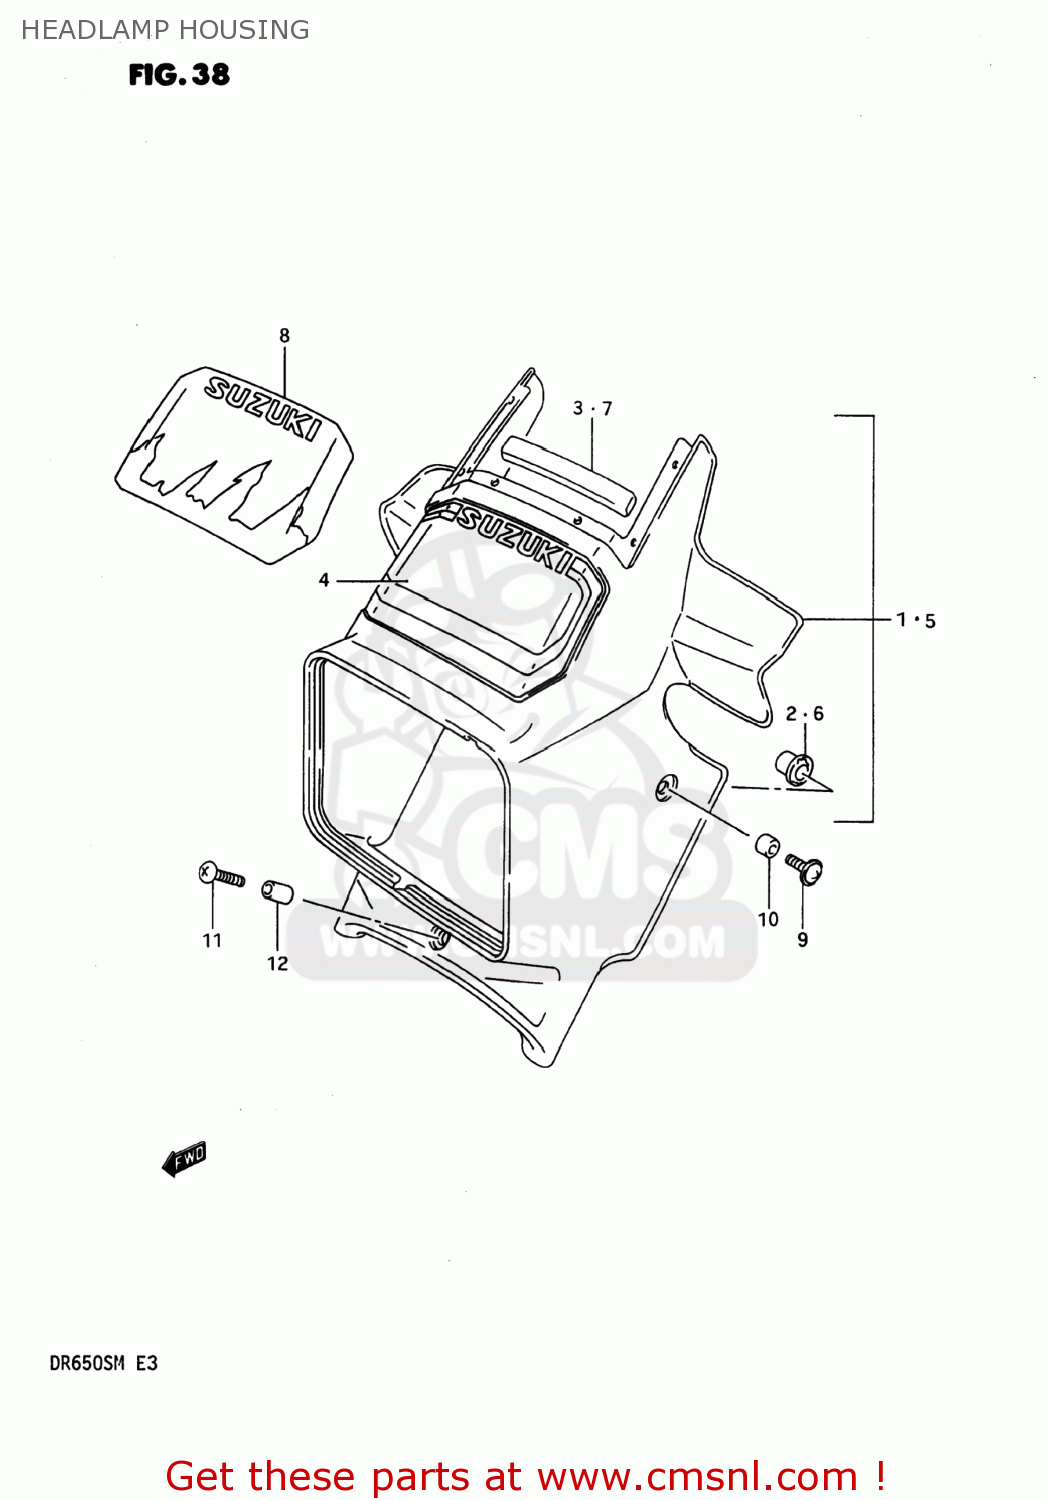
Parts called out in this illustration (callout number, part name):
1	HOUSING ASSEMBLY,HEADLAMP
2	BUSHING,HEADLAMP COVER,SIDE
3	CUSHION,HEADLAMP COVER
4	TAPE,HEADLAMP COVER
5	HOUSING ASSEMBLY,HEADLAMP
6	BUSHING,HEADLAMP COVER,SIDE
7	CUSHION,HEADLAMP COVER
8	TAPE,HEADLAMP COVER
9	SCREW(6X16)
10	SPACER
11	SCREW, LOWER
12	SPACER (6.1X9X31.5)
